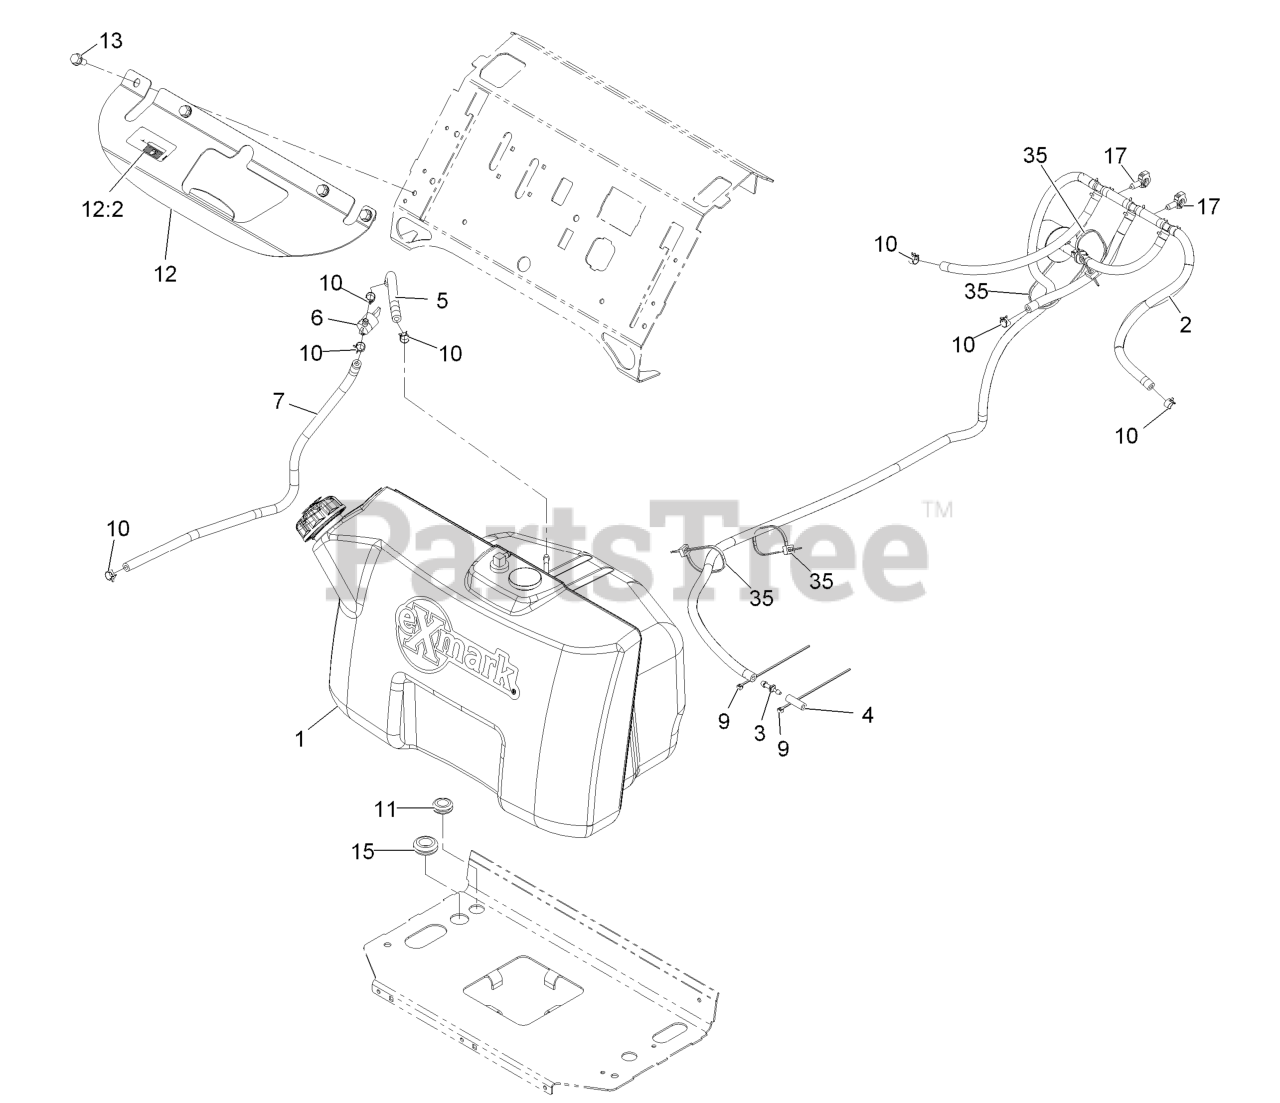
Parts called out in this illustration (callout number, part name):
2	VENT ASM
3	FITTING-STRAIGHT
4	HOSE-FUEL
5	HOSE-FUEL
6	VALVE-FUEL
7	HOSE-FUEL
9	TIE-CABLE
10	CLAMP-HOSE
11	GROMMET
12	BRACKET-TANK
12:2	DECAL-FILL, FUEL
13	SCREW-THD ROLL, HWH
15	GROMMET
17	CLIP-HARNESS
35	TIE-CABLE
